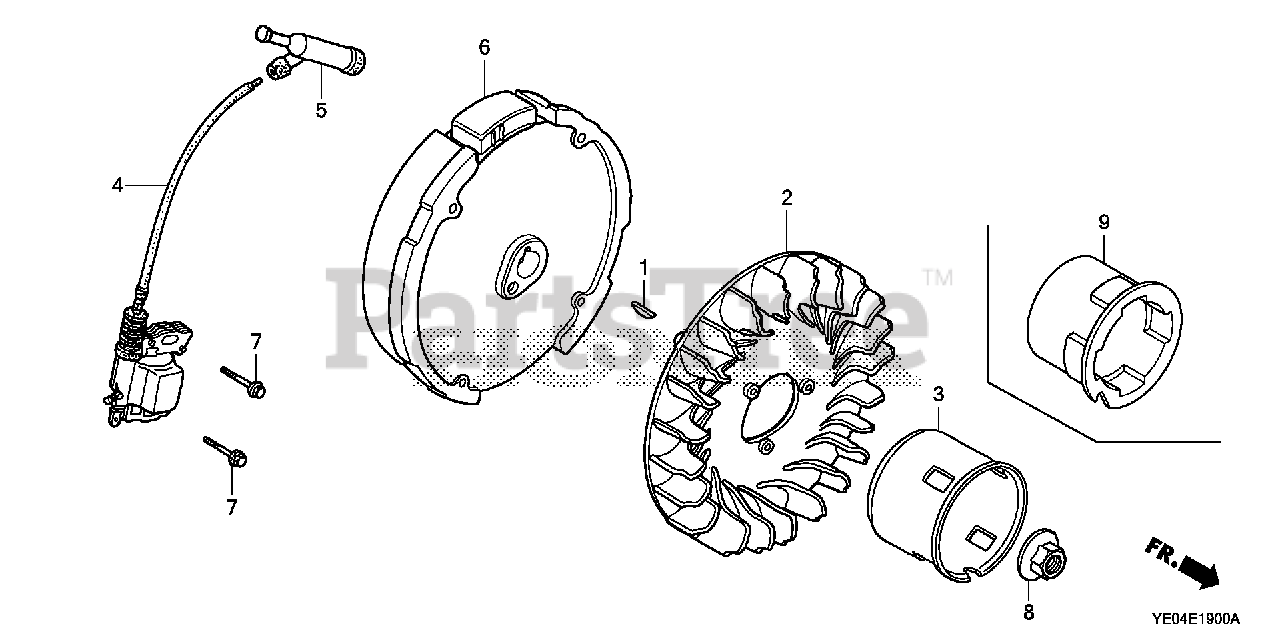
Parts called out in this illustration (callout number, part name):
1	KEY, SPECIAL WOODRUFF (25X18)
2	FAN, COOLING
3	PULLEY, STARTER
4	COIL ASSY., IGNITION (TEC)
5	CAP ASSY., NOISE SUPPRESSOR (TEC)
5	CAP ASSY., NOISE SUPPRESSOR (NGK)
7	BOLT, FLANGE (6X25) Use up to Engine SN 2056819.
8	NUT, SPECIAL (14MM)
9	PULLEY, STARTER
